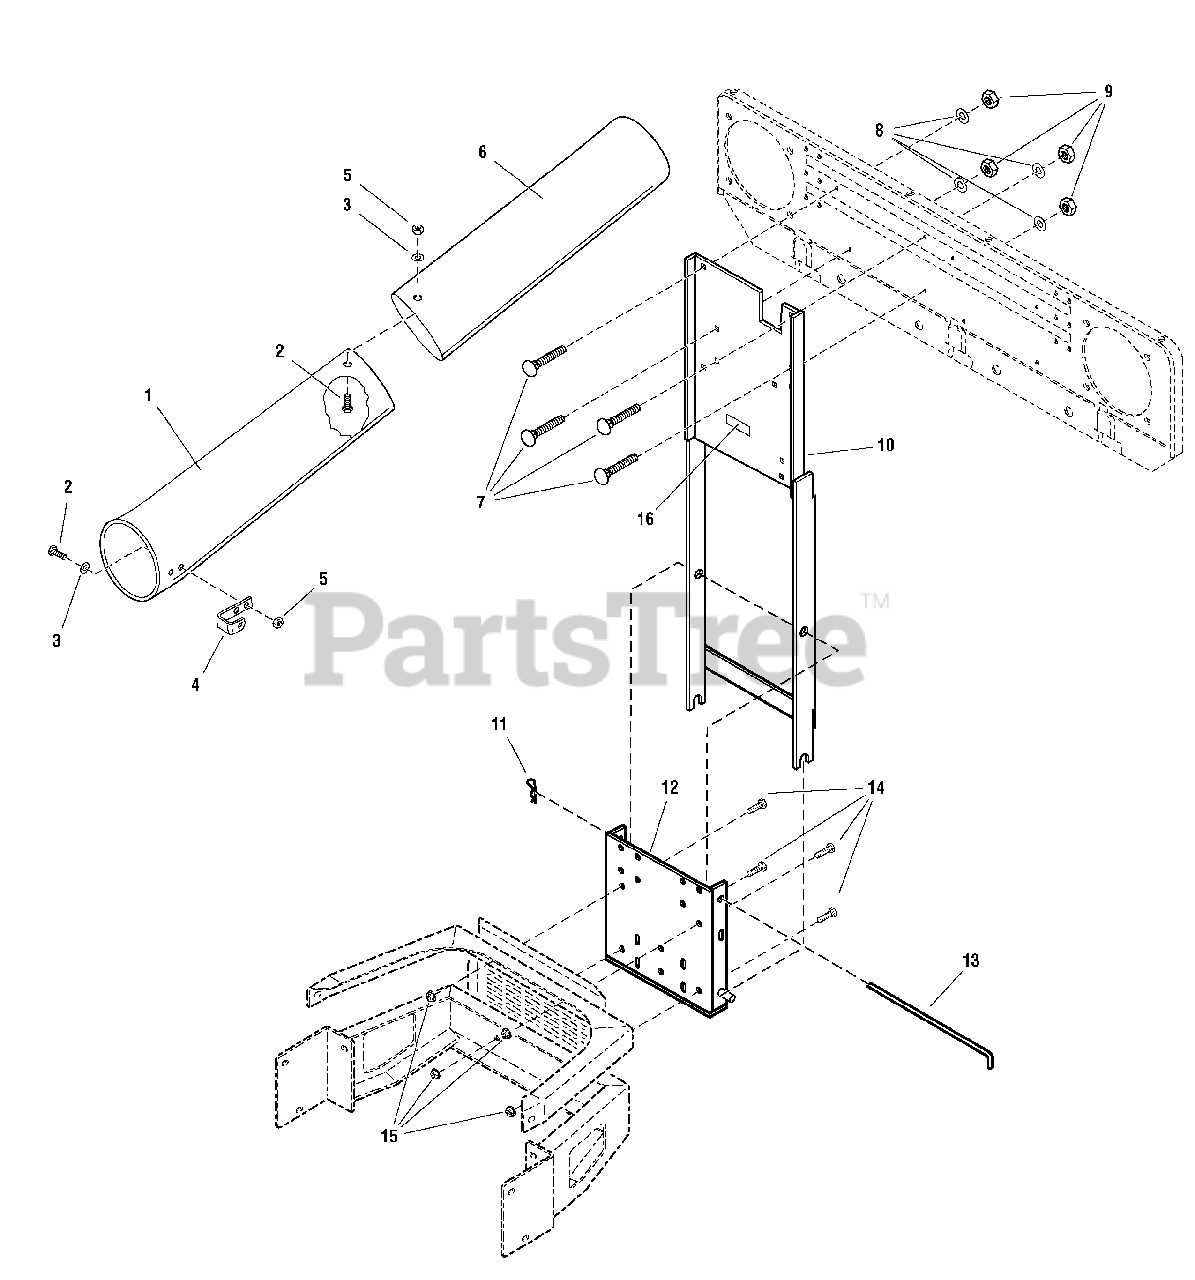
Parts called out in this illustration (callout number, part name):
1	CHUTE, Grass Collector Lower, Black Poly
2	SCREW, Truss Head Phillips, #10, 24 x 3/4 Black
3	WASHER, 3/16 (0.19ID x 0.75OD x .06THK) Black
4	CLIP, Spring, 1.40 x 1.48 Open 3.50LG 0.88WD
5	NUT, Hex Lock, 10-24 with Nylon Insert NC3B Black
6	CHUTE, Grass Collector Middle, Black Poly
7	CARRIAGE BOLT, 5/16-18 x 1 G5 Black
8	LOCKWASHER, Spring, 5/16 Black
9	NUT, Hex 5/16-18 NC-2B Black
10	SUPPORT ASSEMBLY, Triple Collector
11	CLIP, Hair Pin, .125DIA Spring Wire 2.562LG Black
12	PLATE & PINS ASSEMBLY, Hitch Triple Collector Black
13	ROD, Hitch, .625DIA 16.5LG
14	CAPSCREW, Hex Head, 1/2-13 x 1-1/4 G5 Black
15	NUT, Hex Flange Whiz Lock, 1/2-13 Black
16	DECAL, ID Plate
